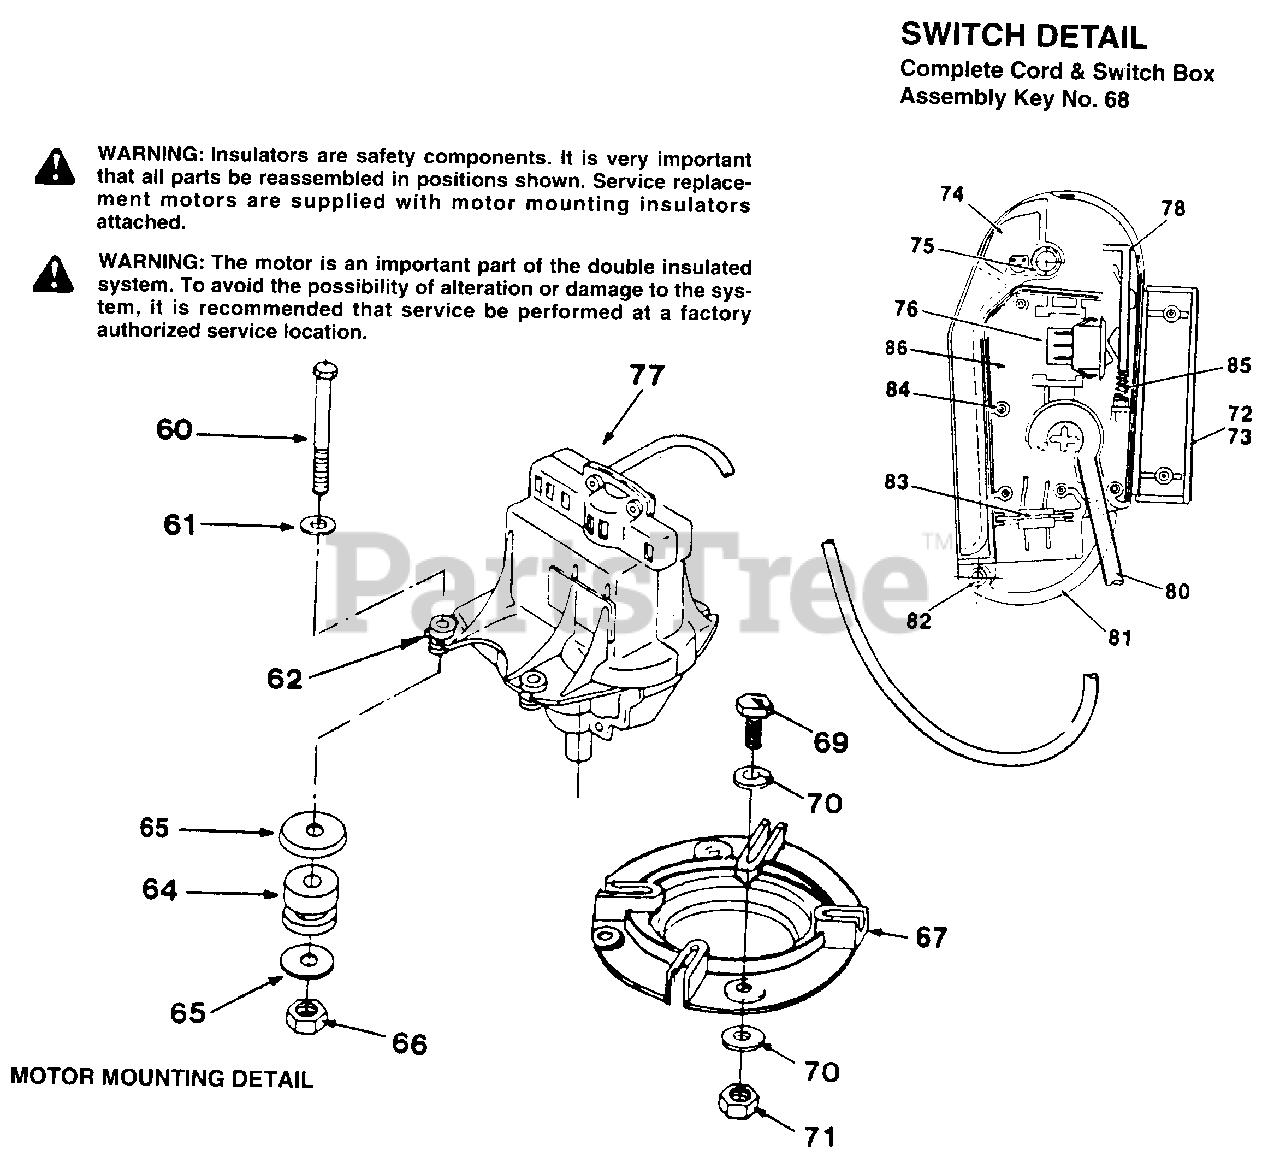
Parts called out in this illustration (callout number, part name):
60	Hex Bolt 1/4-20 x 2" (Grade 5)
61	Flat Washer 1/4"
62	Insulator-Motor Housing
64	Grommet Assembly
65	Flat Washer
66	Nut 1/4-20 Locking
67	Adaptor-Motor Mtg.
69	Hex Bolt 3/8-16 x 1-1/4"
70	Flat Washer 3/8"
71	Nut 3/8-16 Locking
72	Housing-Upper Half
74	Handle-Switch Actuator
75	Spring-Switch Handle
76	Switch
77	Motor & Switch Assembly
78	Latch
80	Cord Assembly
81	Plug Retainer
82	Spring-Plug Retainer
83	Plug Assembly
85	Latch Spring
